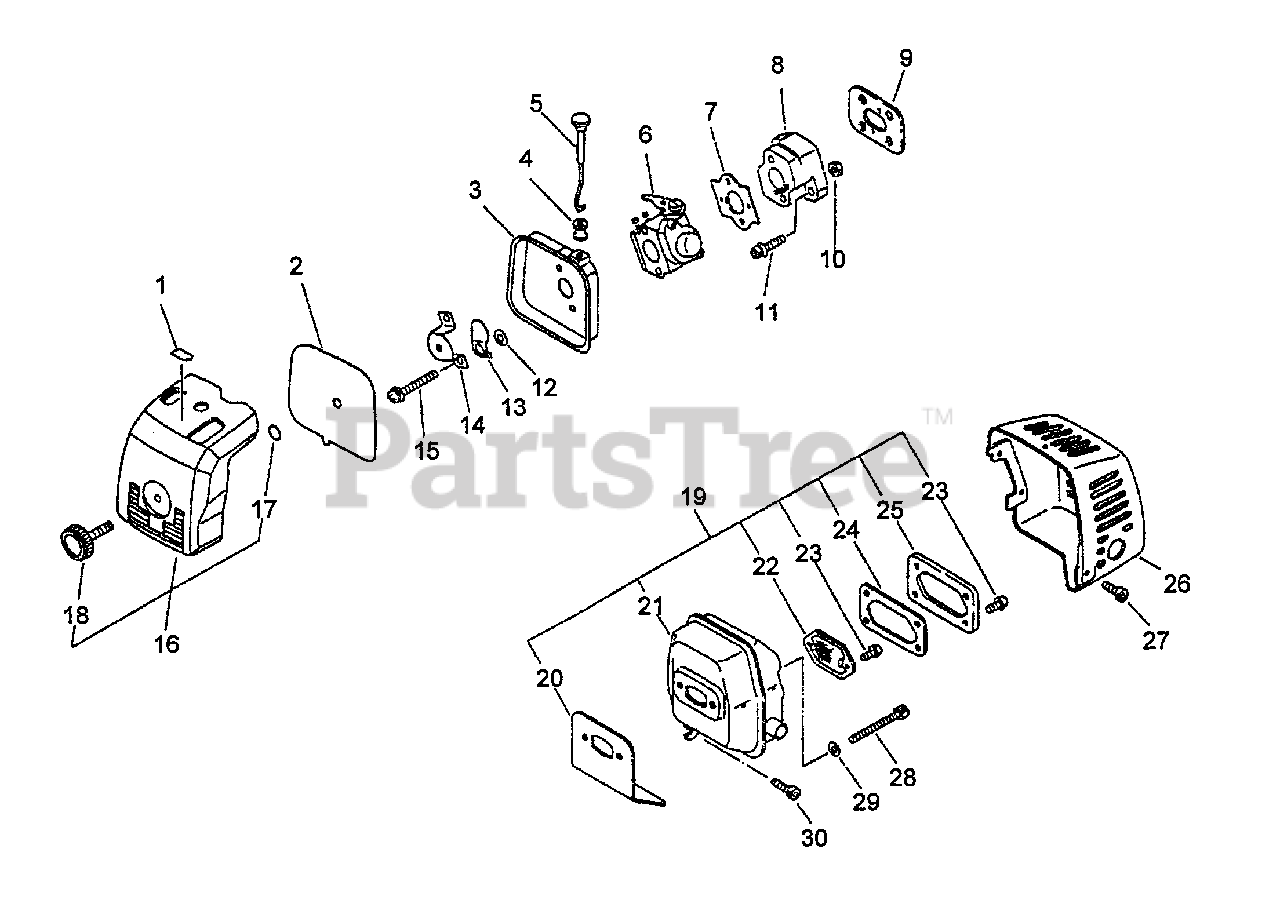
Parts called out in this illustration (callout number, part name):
1	LABEL, CHOKE
2	FILTER, HEAVY-DUTY AIR
3	CASE, AIR FILTER
4	GROMMET, CHOKE
5	ROD, CHOKE
6	CARBURETOR - WT-333
7	GASKET, CARBURETOR
8	INSULATOR, INTAKE
9	GASKET, INTAKE
10	NUT M5
11	BOLT 5×25
12	WASHER 5.2×8×0.8T
13	SHUTTER, CHOKE
14	PLATE, PREVENT
15	BOLT 5×57
16	AIR FILTER COVER ASSY
17	O-RING 3
18	THUMBSCREW
19	MUFFLER ASSY
20	GASKET, MUFFLER
21	MUFFLER
23	SCREW 4×10
24	GASKET, EXHAUST
25	LID, MUFFLER
26	COVER, MUFFLER
27	BOLT 5×14
28	BOLT 5×60
29	WASHER, FLAT 5.5×10×0.8
30	BOLT 5×12
